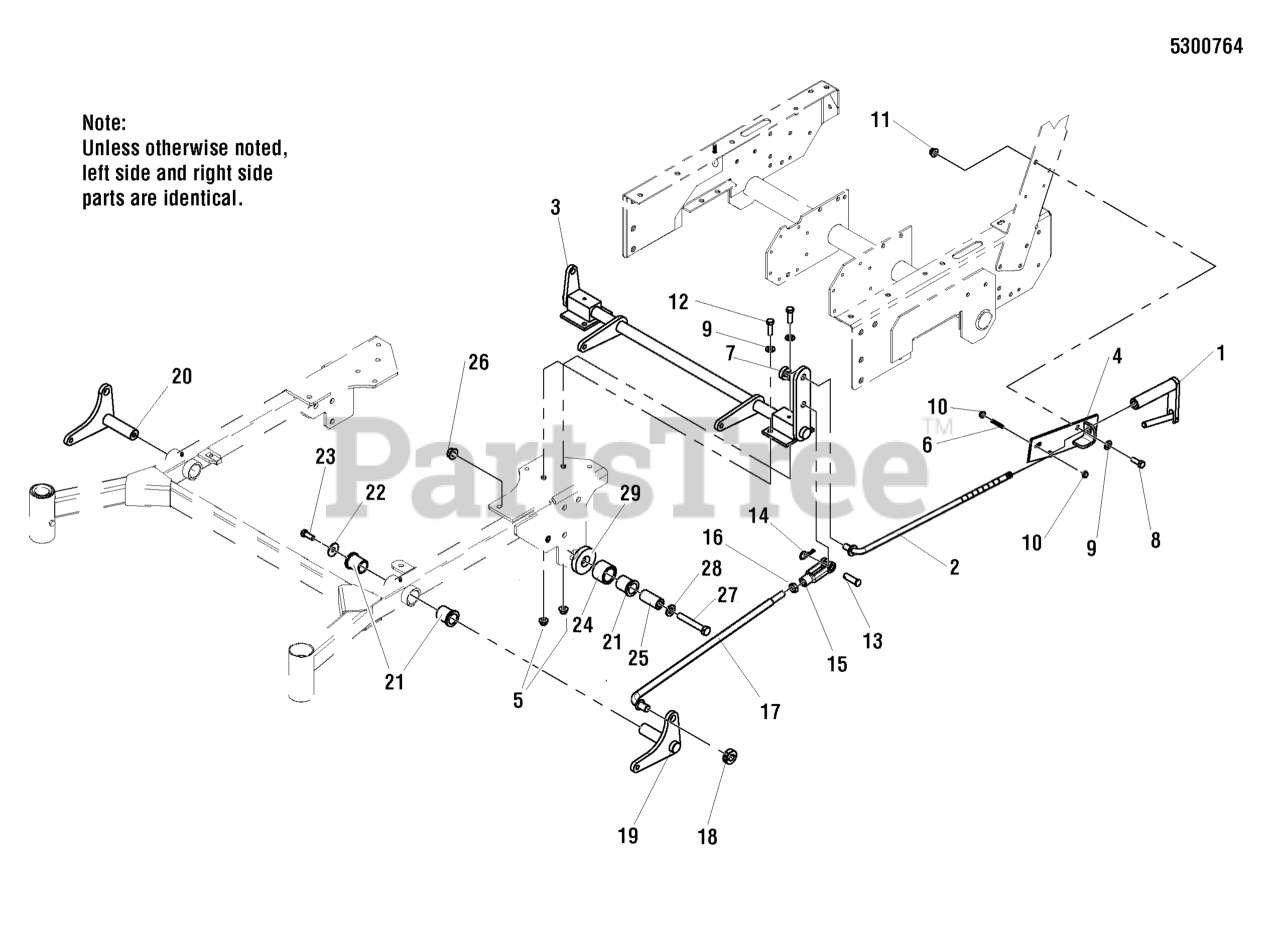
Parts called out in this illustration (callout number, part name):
1	ASSY, CRANK, DECK LIFT
2	ROD, DECK LIFT, REAR
3	WELD, SHAFT, DECK LIFT, REAR
4	WELD, MOUNT, DECK LIFT
5	NUT, 3/8-16 HEX NYLOCK FLANGE
6	SET SCREW, 1/4-20 X 1-1/2" CONE
7	COLLAR, 1/2" SINGLE SPLIT
8	BOLT, 3/8-16 X 3/4" GD5 CZ
9	WASHER, 3/8 SAE
10	NUT, 1/4-20 HEX SERR. FLANGE
11	NUT, 3/8-16 HEX SERRATED FLANGE
12	BOLT, 3/8-16 X 1-1/4" GD5 CZ
13	PIN, CLEVIS, 1/2" X 1-1/2", YZP
14	3/32 X 1-5/8 HAIR PIN CLIP
15	CLEVIS, 1/2-20 STEEL
16	NUT, 1/2-20 HEX JAM
17	ROD, LINK, DECK LIFT, FRONT
18	COLLAR, 5/8" SPLIT
19	WELD, DECK LIFT LEVER, LH
20	WELD, DECK LIFT LEVER, RH
21	BUSHING, FLANGE
22	WASHER, .390 X 1.50 .109 YZ
23	BOLT, 3/8-16 X 3/4, PLT W/PATCH
24	ROLLER
25	SPACER, .52 X 1.00 X 2.09
26	NUT, Hex, Nylon Lock, 1/2-20
27	BOLT, 1/2-13 X 3-1/2, HEX HD, GD5, CZ (SV)
28	WASHER, 1/2 USS
29	WASHER, FRICTION
